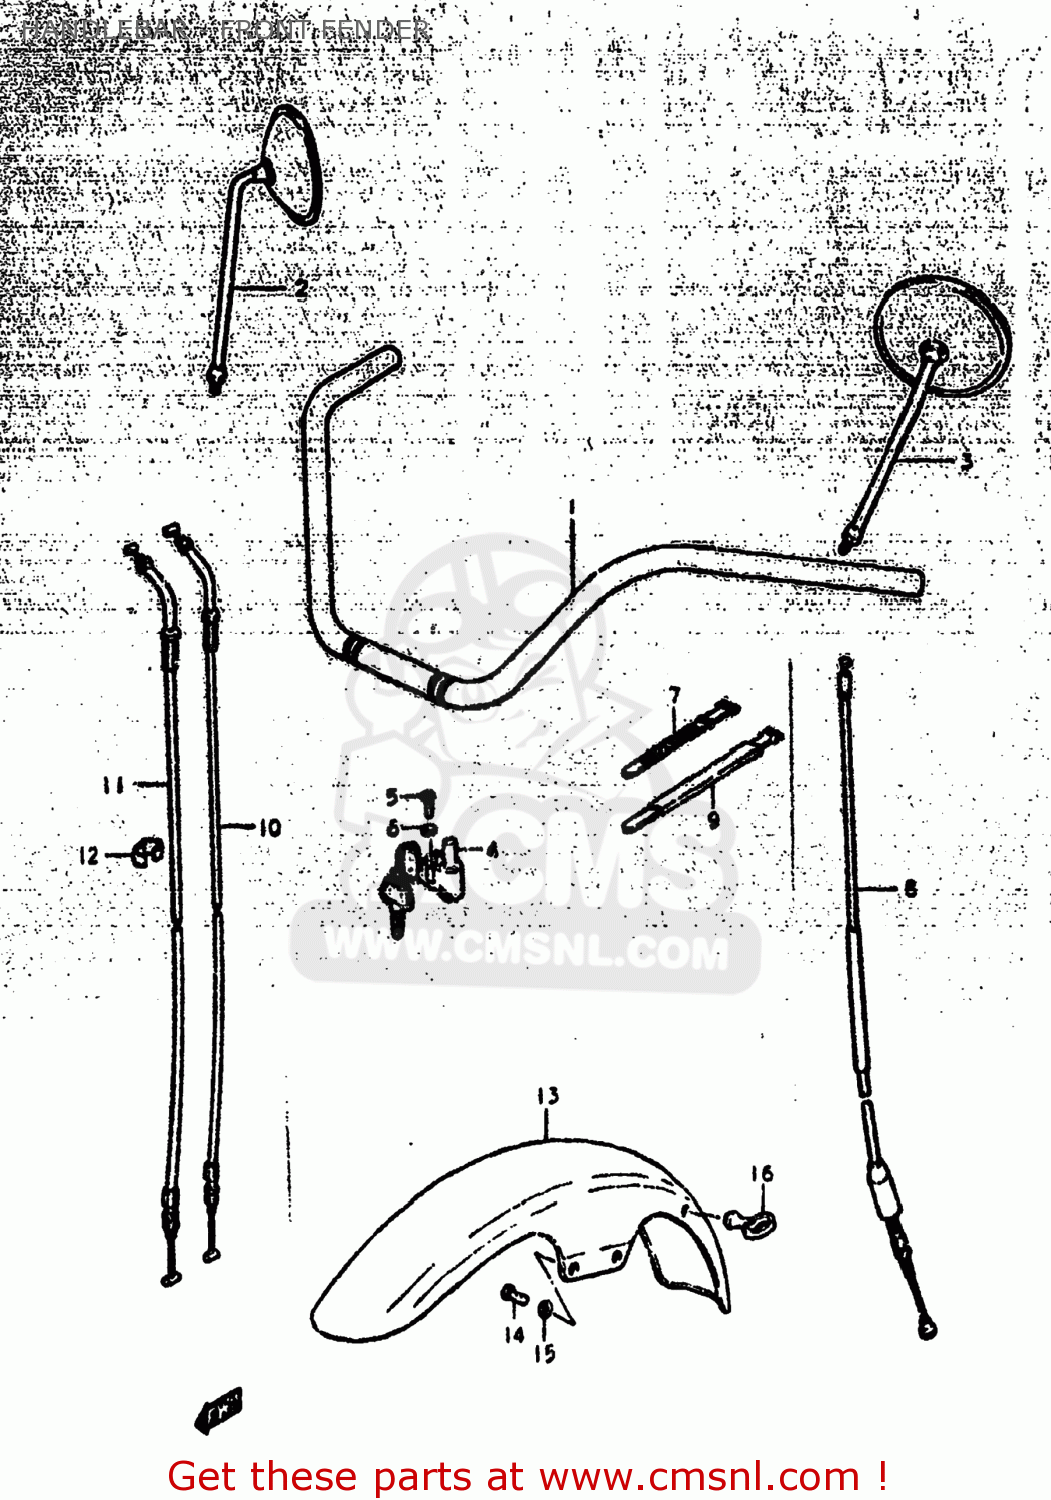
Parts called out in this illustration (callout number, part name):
1	HANDLEBAR
2	MIRROR ASSEMBLY,REAR VIEW
3	MIRROR ASSEMBLY,LEFT
4	LOCK ASSEMBLY,STEERING
5	SCREW
6	LOCK WASHER
7	CLAMP(L:120)
8	CABLE ASSEMBLY,CLUTCH
9	CLAMP
10	CABLE ASSEMBLY,THROTTLE
11	CABLE ASSEMBLY,THROTTLE
12	CLIP
13	FENDER ASSY,FR
14	BOLT
15	LOCK WASHER
16	GUIDE,CABLE
